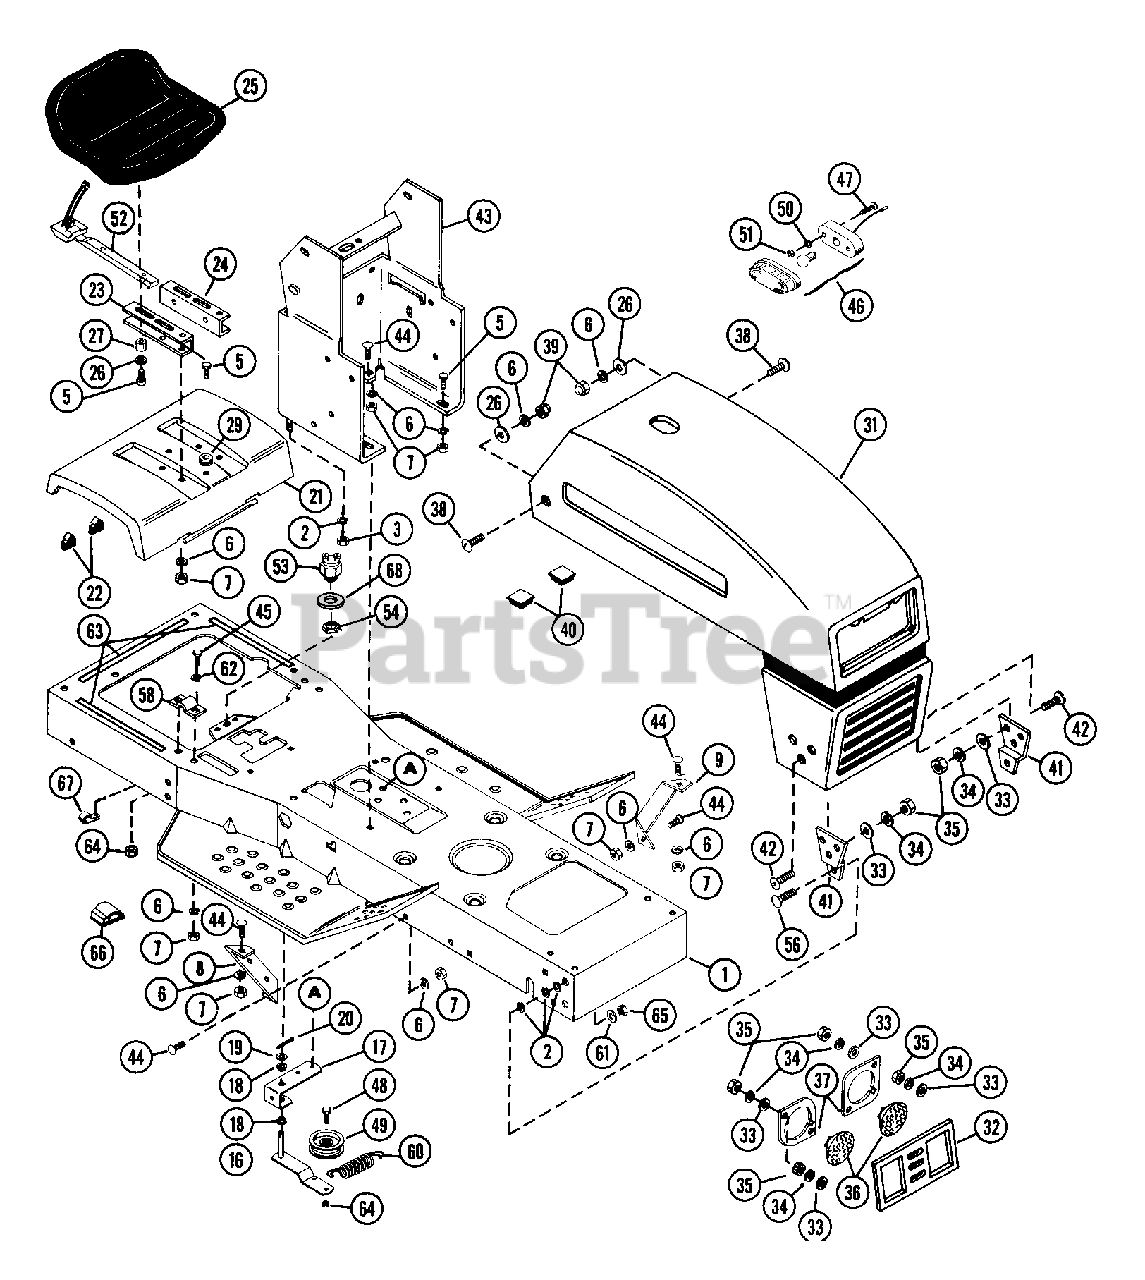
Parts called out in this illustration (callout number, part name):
1	FRAME W/DECALS
2	WSHR-LK .375X.115 HVY PL
3	NUT-HEX .375-16
5	BLT-HEX .31-18X.75 PL GR5
6	WSHR-LK .312X.097 PL HVY
7	NUT-HEX .312-18
8	STRUT RIGHT FOOT BOARD
9	STRUT LEFT FOOT BOARD
10	BLT-RDHDSQNK .31-18X.75 GR5 PL
16	IDLER ARM
17	IDLER PIVOT
18	BSHG-FLG .372X.500X.312X.625NY
19	WSHR-FL-STL.406X.812X.065PL
20	PIN-COTR .12X1.0 PL
21	REAR DECK
23	SEAT CHANNEL R H
24	SEAT CHANNEL L H
25	SEAT V-350
26	WSHR-FL-STL .38X.875X.083 PL
27	SPACER BUSHING .5 X .32 X .21
29	GROMMET, .31 ID
31	HOOD & GRILL W/DECALS YT8
31	HOOD & GRILL W/DECALS YT11
32	HEADLIGHT INSERT
33	WSHR-FL-STL.312X.734X.065PL
34	WSHR-LK .250X.077 HVY PL
35	NUT-HEX .250-20 PL
36	HEAD LIGHT
37	HEAD LIGHT RETAINER RING
38	SCR-MCH .31-18X.50 SLTR PL
39	NUT-CROWN .312-18 PL
40	STOP
41	HOOD HINGE
42	SCRW-MCH .25-20X.38 TRUSS PL
43	DASH BASE
44	BLT-RDHDSQNK .31-18X.75 GR5 PL
45	BLT-HEX .31-18X.75 PL GR2
46	TAIL LIGHT
46	TAIL LIGHT LENS
47	SCR-MCH 10-24X.50 SLTR PL
48	BLT-HEX .38-16X1.75 PL GR5
49	IDLER-FLAT 2.75 X .38 DAYCO
50	WSHR-LK 10X.047 MED PL
51	NUT-HEX 10-24 PL
52	SWITCH SEAT
53	SWITCH-NEUTRAL START N.O.
54	NUT- .562-18
56	BLT-RDHDSQSHNK .38-16X1.00 PL
60	SG-TENS .080X.470X4.88 WLD 30
61	WSHR-FL-STL .438X1.0X.083 PL
62	WSHR-LK-EXT .313X.030 PL
63	1/4 X 3/4 X 1 IN FOAM TAPE
64	NUT-LK .375-16 PL
65	NUT-LK-CTR .375-16 GR A PL
66	WIRE CLIP
68	WSHR-FL-STL .811X1.25X.005
